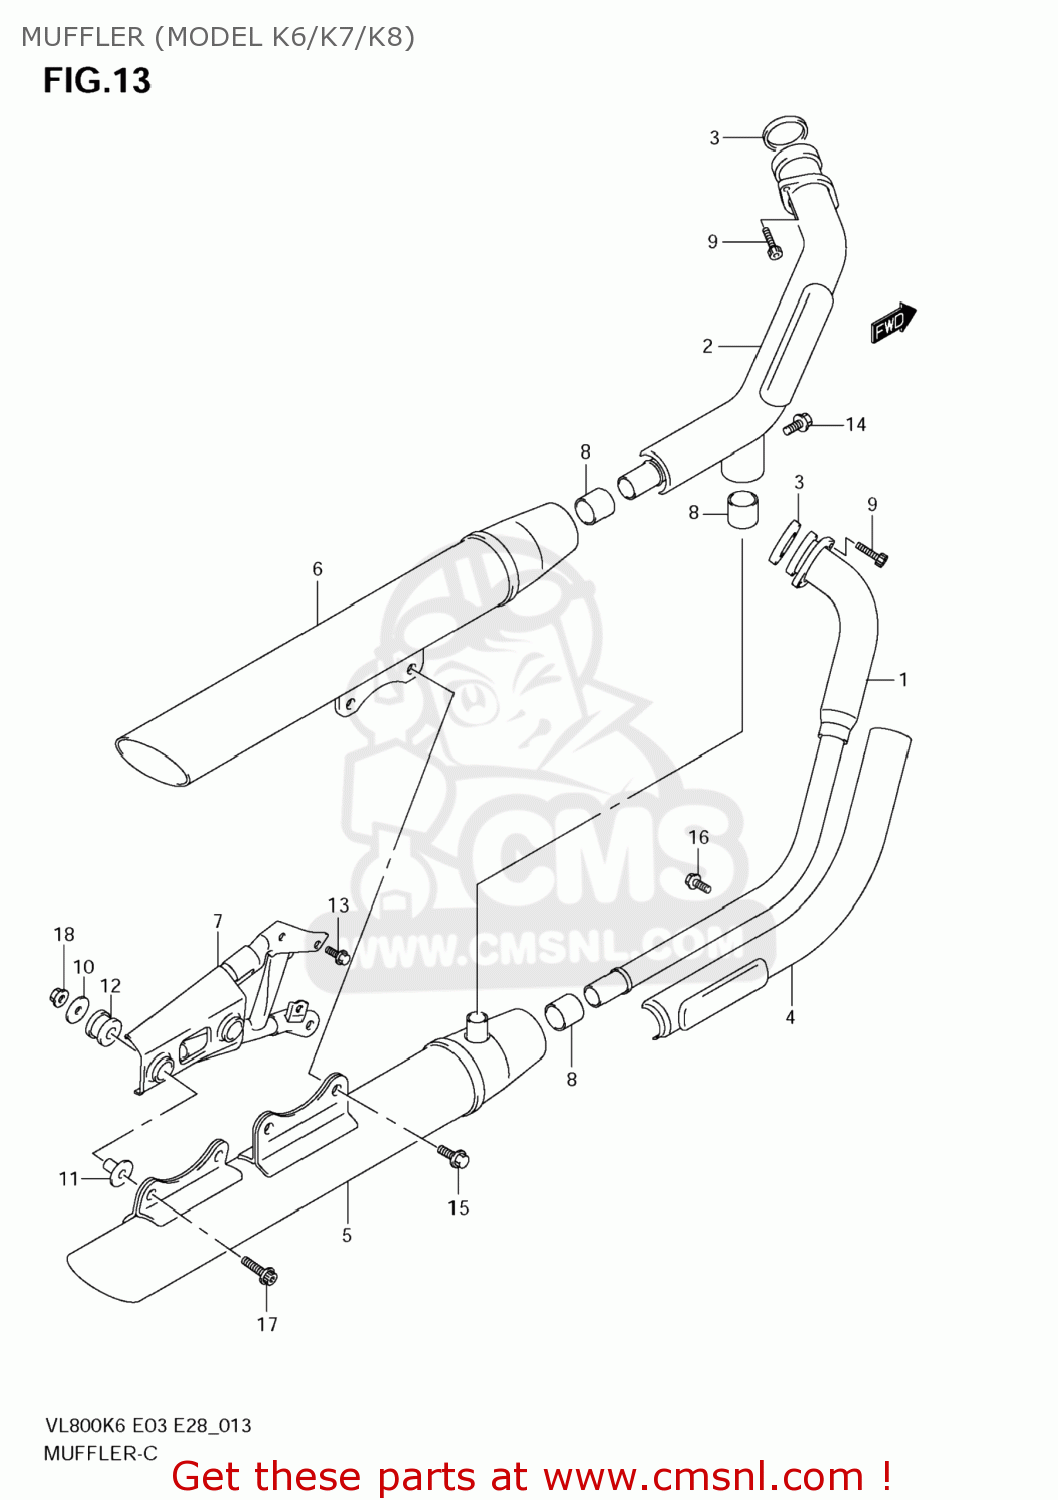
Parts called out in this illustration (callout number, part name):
1	PIPE,EXHAUST FR
2	PIPE,EXHAUST RR
3	GASKET,EXHAUST PIPE (NAS)
4	COVER,EXHAUST FRONT
5	BODY,MUFFLER FR
6	BODY,MUFFLER RR
7	BRACKET,MUFFLER SUPPORT
8	CONNECTOR,MUFFLER
9	BOLT(8X25)
10	WASHER (8.5X33X1.6)
11	SPACER(8.6X12X27.1)
12	CUSHION
13	BOLT
14	BOLT
15	BOLT
16	BOLT
17	BOLT(8X16)
18	NUT
